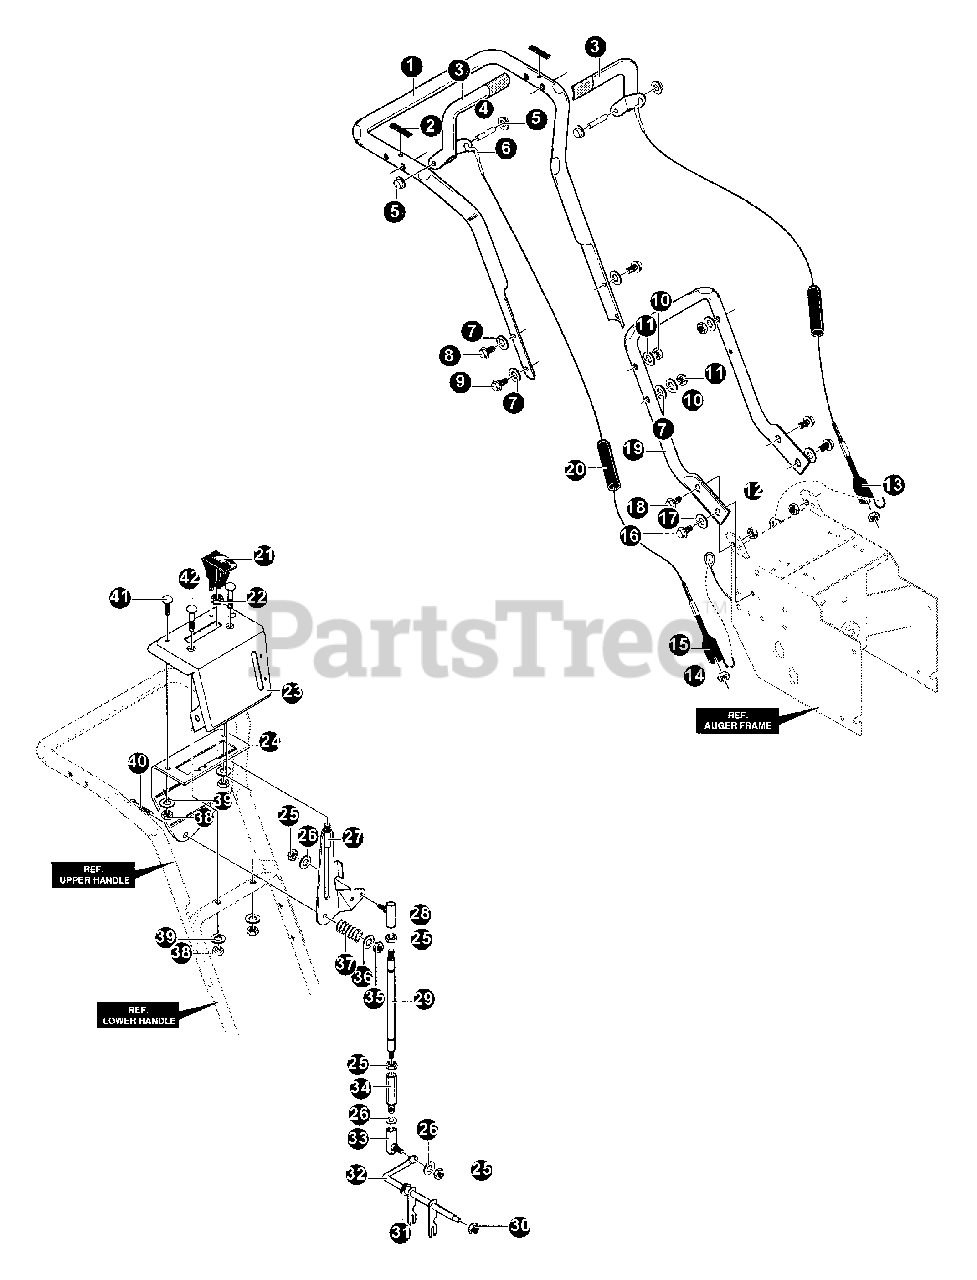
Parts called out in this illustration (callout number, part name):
1	HANDLE - UPPER
2	BUMPER, RECT
3	CLUTCH HANDLES SET
4	PIN, PIVOT CLUTCH
5	PUSHNUT
6	CABLE, CLUTCH
7	WASHER
8	SCREW - 3/8-16 X 3.00"
9	SCREW - 3/8-16 X 2"
10	LOCKWASHER
11	NUT - 3/8-16
12	NUT - 5/16-18
13	SPRING
14	NUT - 1/4-20
15	SPRING, AUGER CLUTCH
16	SCREW - 5/16-18 X 1/2"
17	LOCKWASHER
18	SCREW - 5/16-18 X 3/4"
19	HANDLE - LOWER
20	BOOT, CLUTCH SPRING
21	KNOB, SHIFT
22	NUT - 3/8-16
23	PANEL, CONTROL
24	BRACKET, SHIFT CONTROL
25	NUT - 5/16-24
26	LOCKWASHER
27	SHIFT LEVER ASSY
28	JOINT, SHIFT BALL
29	ROD, SPEED CONTROL
30	NUT - 3/8-16
31	BEARING, FLANGE
32	YOKE ROD ASSY
33	JOINT, SHIFT BALL
34	ADAPTOR, ROD
35	NUT - 5/16-18
36	WASHER
37	SPRING
38	NUT - 1/4-20
39	LOCKWASHER
40	SCREW - 5/16-18 X 1-3/4"
41	BOLT - 1/4-20 X 2.00"
42	BOLT - 1/4-20X.63"
